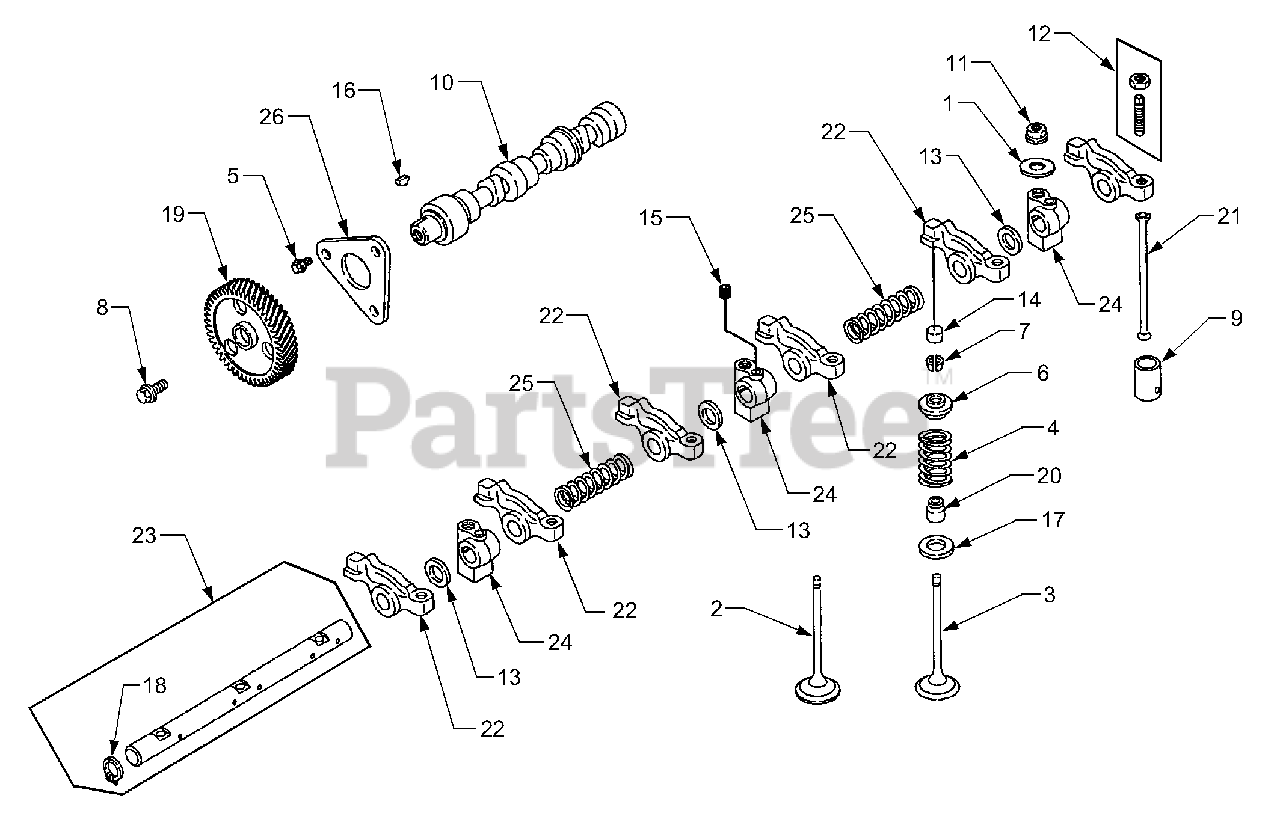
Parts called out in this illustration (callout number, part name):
1	Washer, Flat
2	Valve, Exhaust
3	Valve, Intake
4	Spring, Valve
5	Screw, Hex, 6mm
6	Retainer, Valve
7	Keeper, Valve, Set of 2
8	Screw, Metric
9	Tappet, Valve
11	Nut, Hex Metric
12	Adjuster, Rocker Arm
13	Washer, Spacer
14	Cap, Valve
15	Screw, Metric
16	Key, Timing
17	Seat, Valve Spring
20	Seal, Valve
22	Arm, Rocker
23	Shaft, Rocker Arm
24	Support, Rocker Arm
25	Spring, Rocker Shaft
26	Retainer, Camshaft
